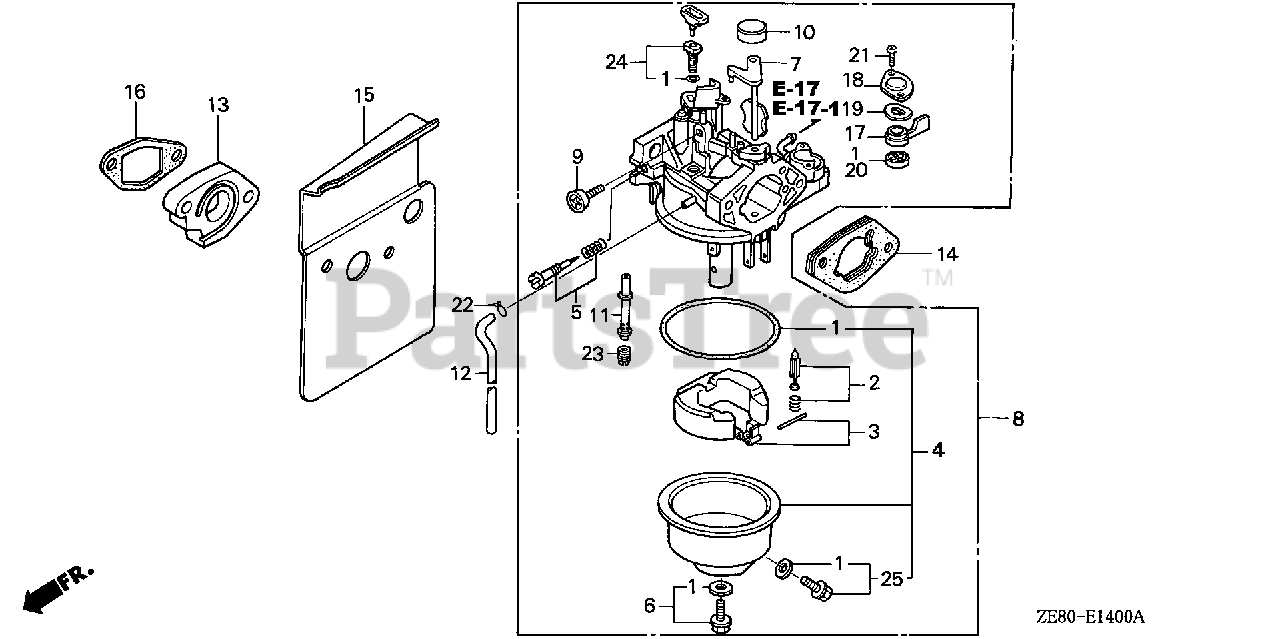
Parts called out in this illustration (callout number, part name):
1	GASKET SET
2	VALVE SET, FLOAT
4	CHAMBER SET, FLOAT
6	SCREW SET
7	CHOKE SET (CARBURETOR NO.)
8	CARBURETOR ASSY. (BE41A B)
9	SCREW, THROTTLE STOP
10	CAP, CHOKE DUST (CARBURETOR NO.)
11	NOZZLE, MAIN
13	INSULATOR, CARBURETOR
14	SPACER, CARBURETOR
15	GASKET, CARBURETOR
16	GASKET, INSULATOR (NOT AVAILABLE)
23	JET, MAIN (#80)
23	JET, MAIN (#82)
23	JET, MAIN (#85)
24	JET SET, PILOT (#45)
